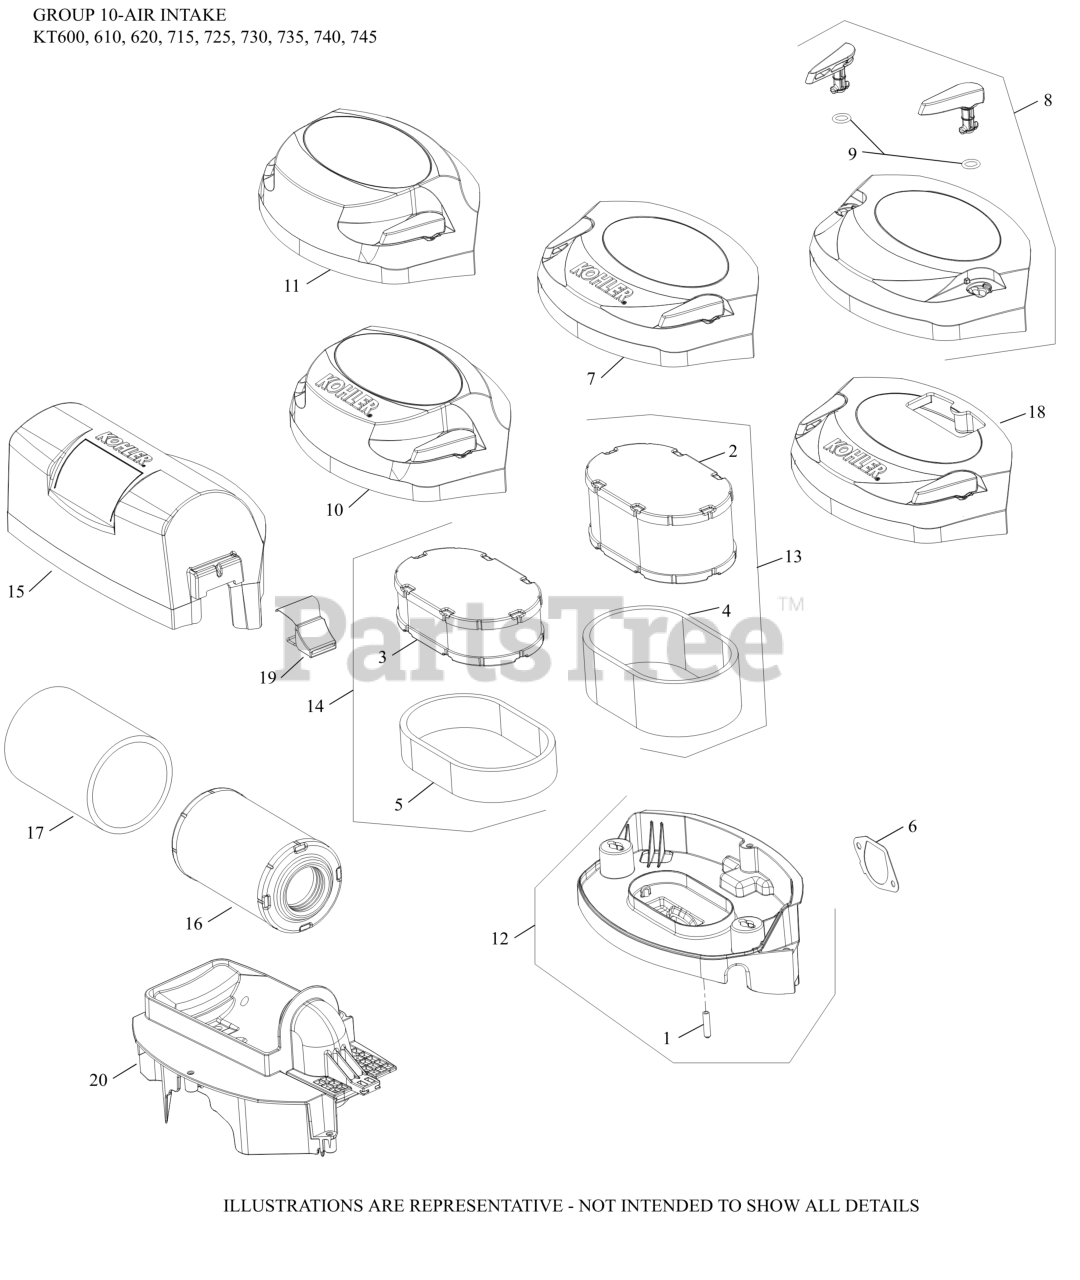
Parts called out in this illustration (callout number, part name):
1	CAP, MASKING
3	ELEMENT, AIR FILTER
5	ELEMENT, PRE-CLEANER
6	GASKET, AIR CLEANER BASE
7	COVER ASSEMBLY, AIR CLEANER
12	BASE ASSY, AIR CLEANER
